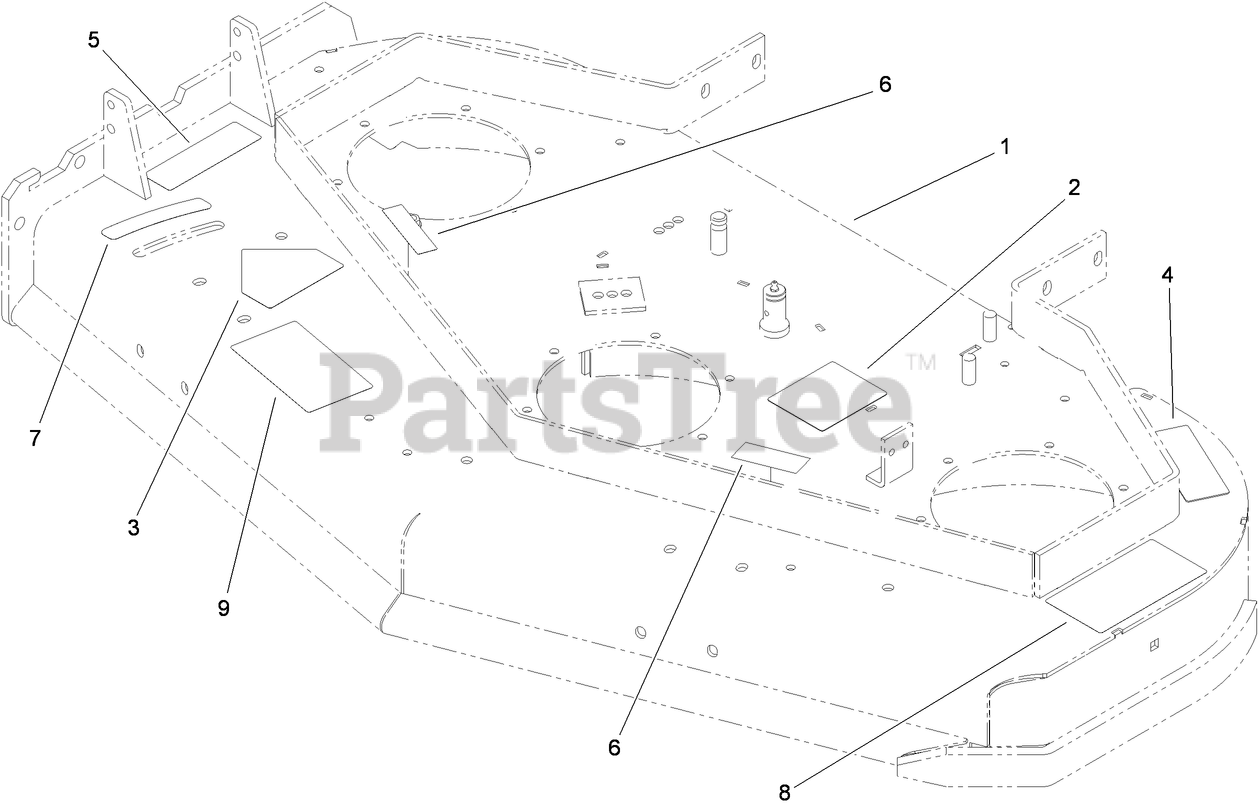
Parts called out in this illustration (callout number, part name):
1	48 INCH DECK ASM
2	DECAL-ROUTING, BELT
3	DECAL-DANGER
4	DECAL-TORQUE, BOLT
5	DECAL-WARNING
6	DECAL-COVER, MISSING
7	DECAL-SETTING, BAFFLE
8	DECAL-DANGER, THROWN OBJECT
9	DECAL-ADJUSTMENT, BAFFLE
